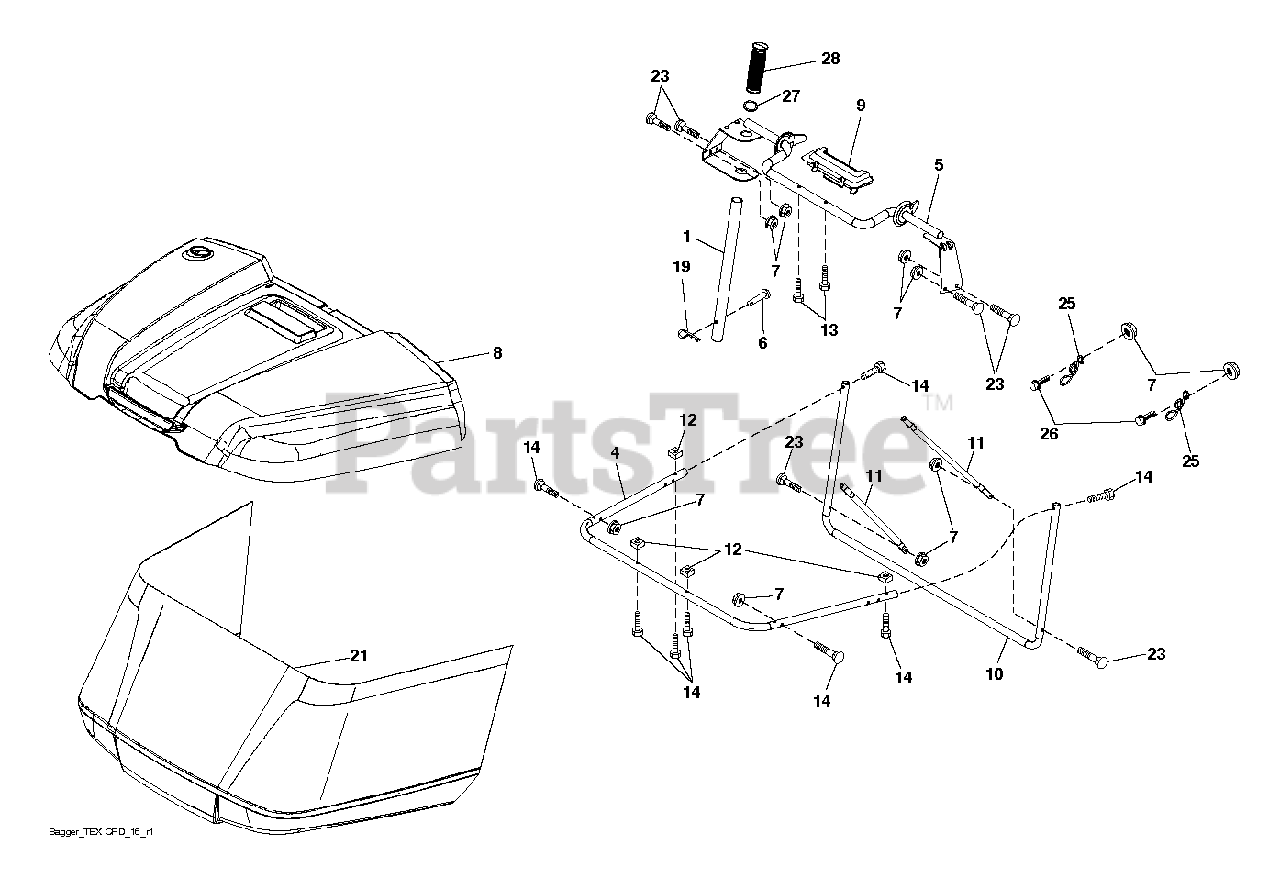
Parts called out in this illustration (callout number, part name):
1	TUBE.PNT.HDL.BAGGER.
6	RIVET,DRILLED
7	NUT T
19	PIN.COTTER.5/16.BOW TI
26	SCREW HEX CRT
28	GRIP.HANDLE.BLACK
